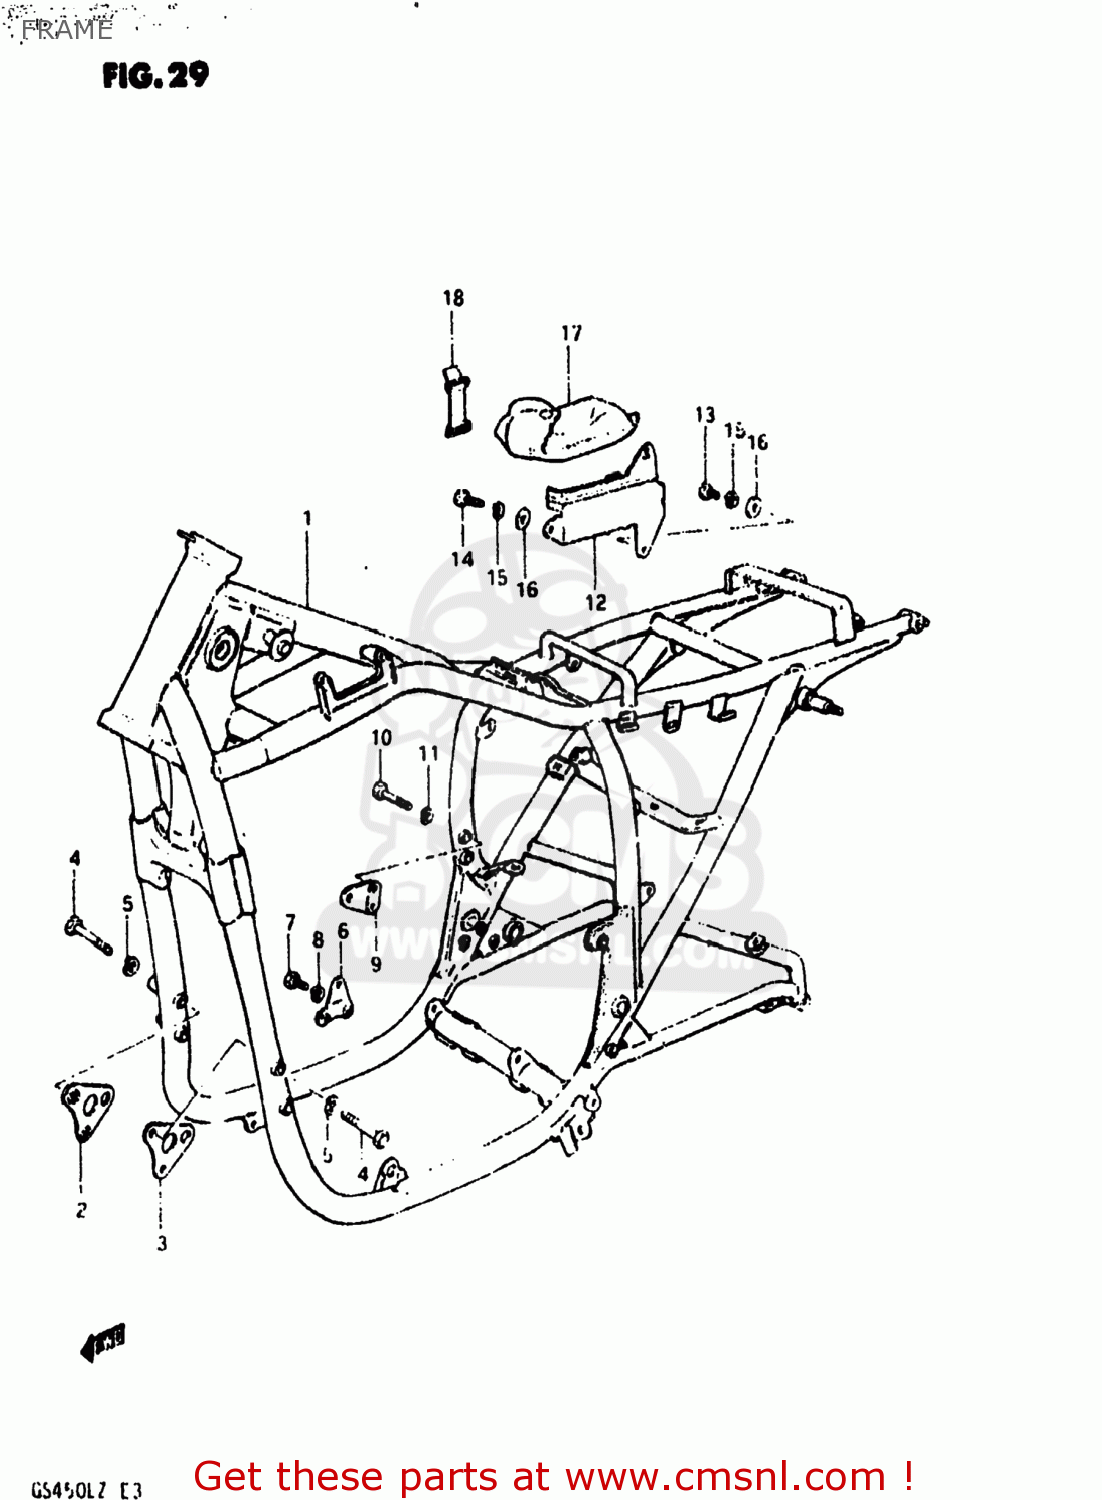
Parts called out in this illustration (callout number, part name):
1	FRAME
2	PLATE,ENGINE MOUNTING
3	PLATE,ENGINE MOUNTING
4	BOLT
5	LOCK WASHER
6	PLATE,ENGINE MOUNTING
7	BOLT
8	LOCK WASHER
9	PLATE,ENGINE MOUNTING
10	BOLT 8X45
11	LOCK WASHER
12	HOLDER,TOOL
13	SCREW 6X12
14	SCREW
15	LOCK WASHER
16	WASHER
17	TOOL SET
18	BAND
